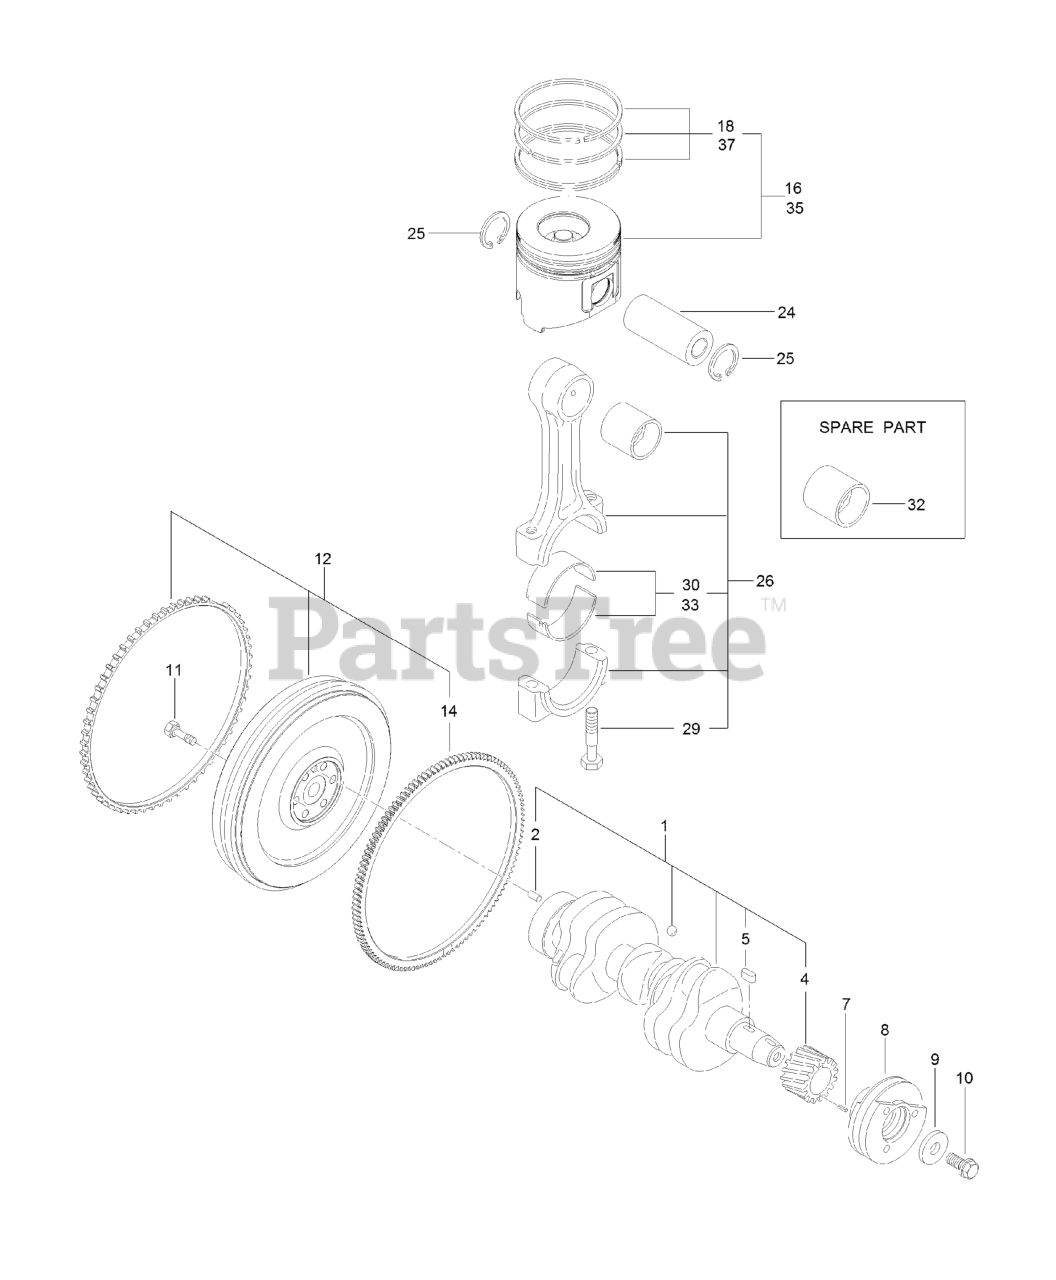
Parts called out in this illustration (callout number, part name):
1	CRANKSHAFT ASM
7	PIN-SPRING
8	PULLEY-V
12	FLYWHEEL ASM
16	PISTON ASM
18	PISTON RING ASM
26	CONNECTING ROD ASM
30	PIN-CRANK
32	PIN-PISTON
33	PIN-CRANK (.25)
35	PISTON ASM (0.25 O S)
37	RING SET (0.25 O S)
